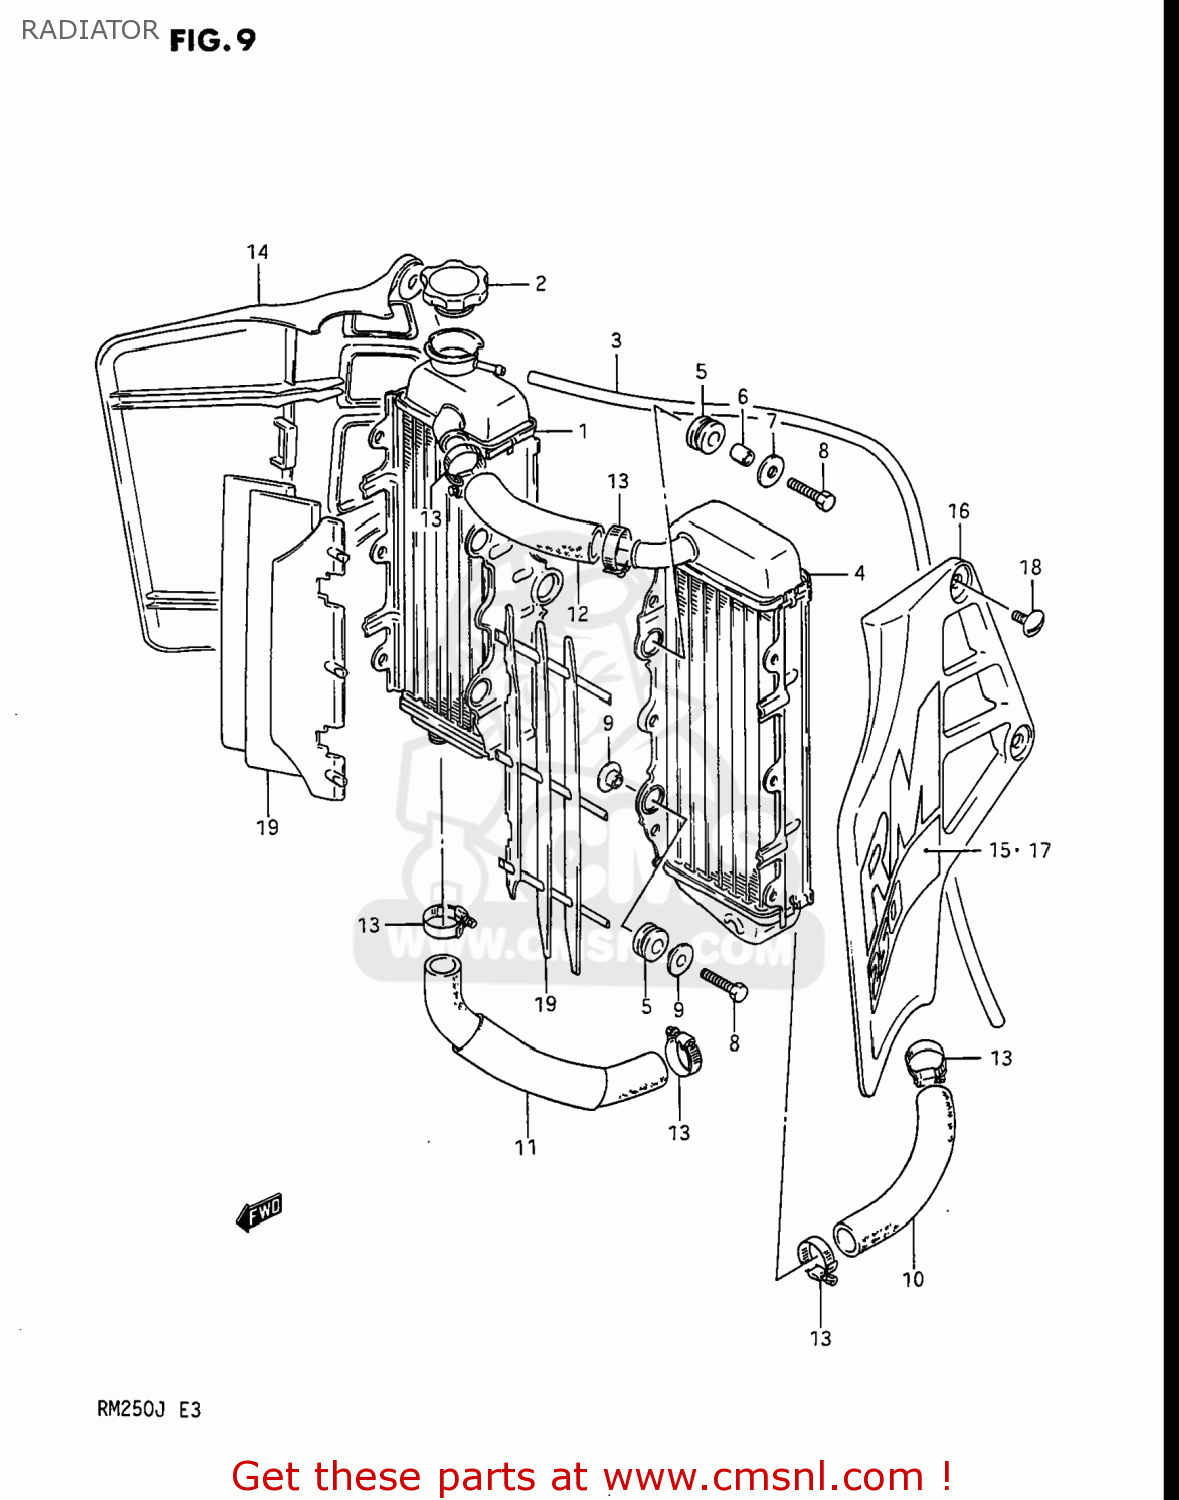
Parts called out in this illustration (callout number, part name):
1	RADIATOR COMP,WATER,RIGHT
2	CAP,RADIATOR 1.1
3	HOSE
4	RADIATOR,WATER,L
5	CUSHION,RADIATOR LWR
6	SPACER(6.5X10.5X12)
7	WASHER (6.5X24X1.6)
8	BOLT
9	WASHER,RDTR SPRT
10	HOSE,RADIATOR INLET
11	HOSE,RADIATOR OUTLET
12	HOSE,RADIATOR
13	CLAMP
14	COVER,RADIATOR,R
15	EMBLEM,RADIATOR COVER
16	COVER,RADIATOR,L
17	EMBLEM,RADIATOR COVER
18	SCREW (6X12)
19	LOUVER,RADIATOR
